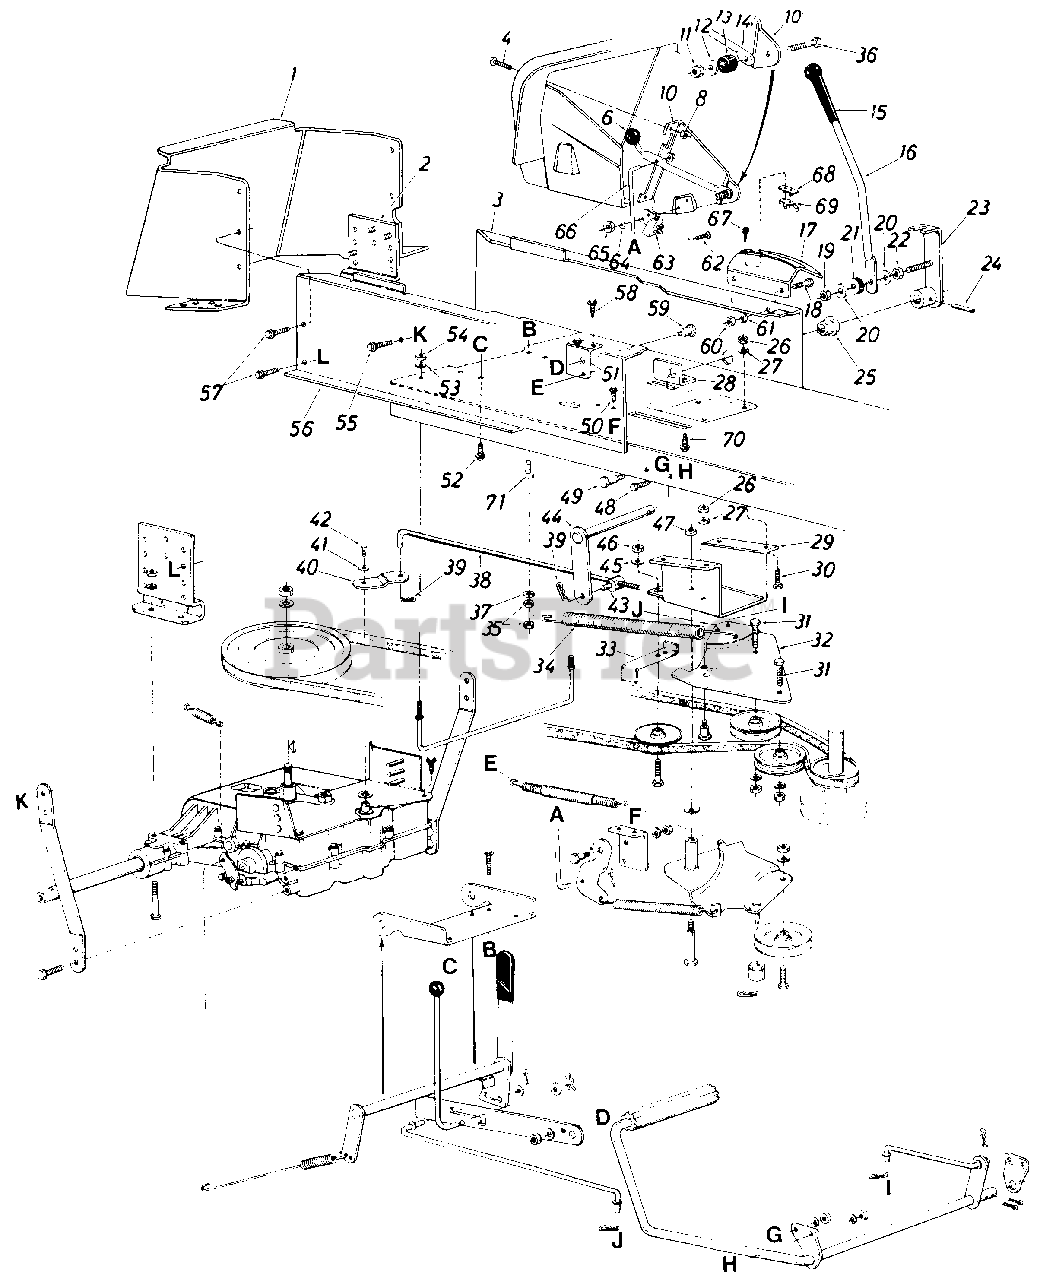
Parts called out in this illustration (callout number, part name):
1	Hitch Plate
2	Transaxle Support Bracket
3	Side Panel Upper Frame L.H.
4	Truss. Mach. Scr. 1/4-20 x .50" Lg.
6	Ball Knob
8	Hex Sems Nut 1/4-20 Thd*
10	Deck Clutch Control Brkt.
11	Hex Cent. L-Nut 1/4-20 Thd.
12	Fl-Wash. .281" I.D. x .734" O.D. x .063 Thk.
13	Rubber Wash. .330" I.D. x .87" O.D. x .32 Thk.
14	Blade Clutch Lever
16	Shift Lever
17	Shift Bracket
18	Hex Bolt 5/16-18 x .62" Lg.
19	Hex Cent. L-Nut 5/16-18 Thd.
20	Fl-Wash. .344" I.D. x .875" O.D. x .063 Thk.
21	Rubber Wash. .330" I.D. x .87" O.D. x .32 Thk.
22	Hex Nut 5/16-18 Thd.
23	Handle Mount Brkt. Ass'y.
24	Spring Pin Spiral 1/4" Dia. x 1.5" Lg.
25	Plastic Hex Bearing .625" I.D.
26	Hex Nut 5/16-18 Thd.*
27	L-Wash. 5/16" I.D.
28	Speed Control Shaft Brkt.
29	Transaxle Clutch Support Brkt.
30	Hex Bolt 5/16-18 x 2.50" Lg.
31	Hex Bolt 3/8-16 x 1.25" Lg.*
32	Idler Bracket Ass'y.
35	Hex Cent. L-Nut 1/4-20 Thd.
36	Hex Bolt 1/4-20 x 1.25" Lg.
37	L-Wash. 1/4" I.D.
38	Shift Link
39	Hairpin Cotter 3/8"
40	Shifter Bracket
41	Belleville Wash. .25" I.D. x.375" O.D.
42	Hex Bolt 1/4-28 x .62" Lg.
43	Pivot Bushing
44	Speed Control Shaft Ass'y.
45	Fl-Wash. .385" I.D. x .87" O.D. x .060 Thk.
46	Hex Cent. L-Nut 3/8-24 Thd.
47	Hex Cent. L-Nut 3/8-16 Thd.
48	Hex Bolt 3/8-16 x .62" Lg.
49	Shoulder Bolt .500" Dia. x .340" Lg. (3/8-16)
50	Hex Thd. Rolling Scr. 1/4-20 x.50" Lg.
51	Parking Brake Cam Mtg. Brkt.
52	Hex Thd. Rolling Scr. 1/4-20 x.50" Lg.
53	L-Wash. 1/4" I.D.
54	Hex Nut 1/4-20 Thd.
55	Hex Wash. Hd. TT-Tap Scr. 3/8-16 x .5" Lg.
56	Side Panel Upper Frame R.H.
57	Hex Thd. Rolling Scr. 5/16-24 x .50" Lg.
58	Hex Thd. Rolling Scr. 1/4-20 x.50" Lg.
59	Shoulder Bolt .435" Dia. x .160 (5/16-18)
60	Hex Nut 5/16-18 Thd.*
61	L-Wash. 5/16" I.D.
62	Truss Mach. Scr. #10-24 x .50" Lg.
63	Safety Switch
64	Ext. L-Wash. #10 I.D.
65	Hex Nut #10-24 Thd.
66	Deck Control Rod
67	Hex Wash. Hd. Scr. #8 x .50" Lg.
68	Insulator Nut Plate
69	Spring Switch
70	Hex Wash. Hd. AB-Tap Scr. 5/16 x .75" Lg.
71	Hex Wash. Hd. TT-Tp Scr. 1/4 X 1.5" Ln.
